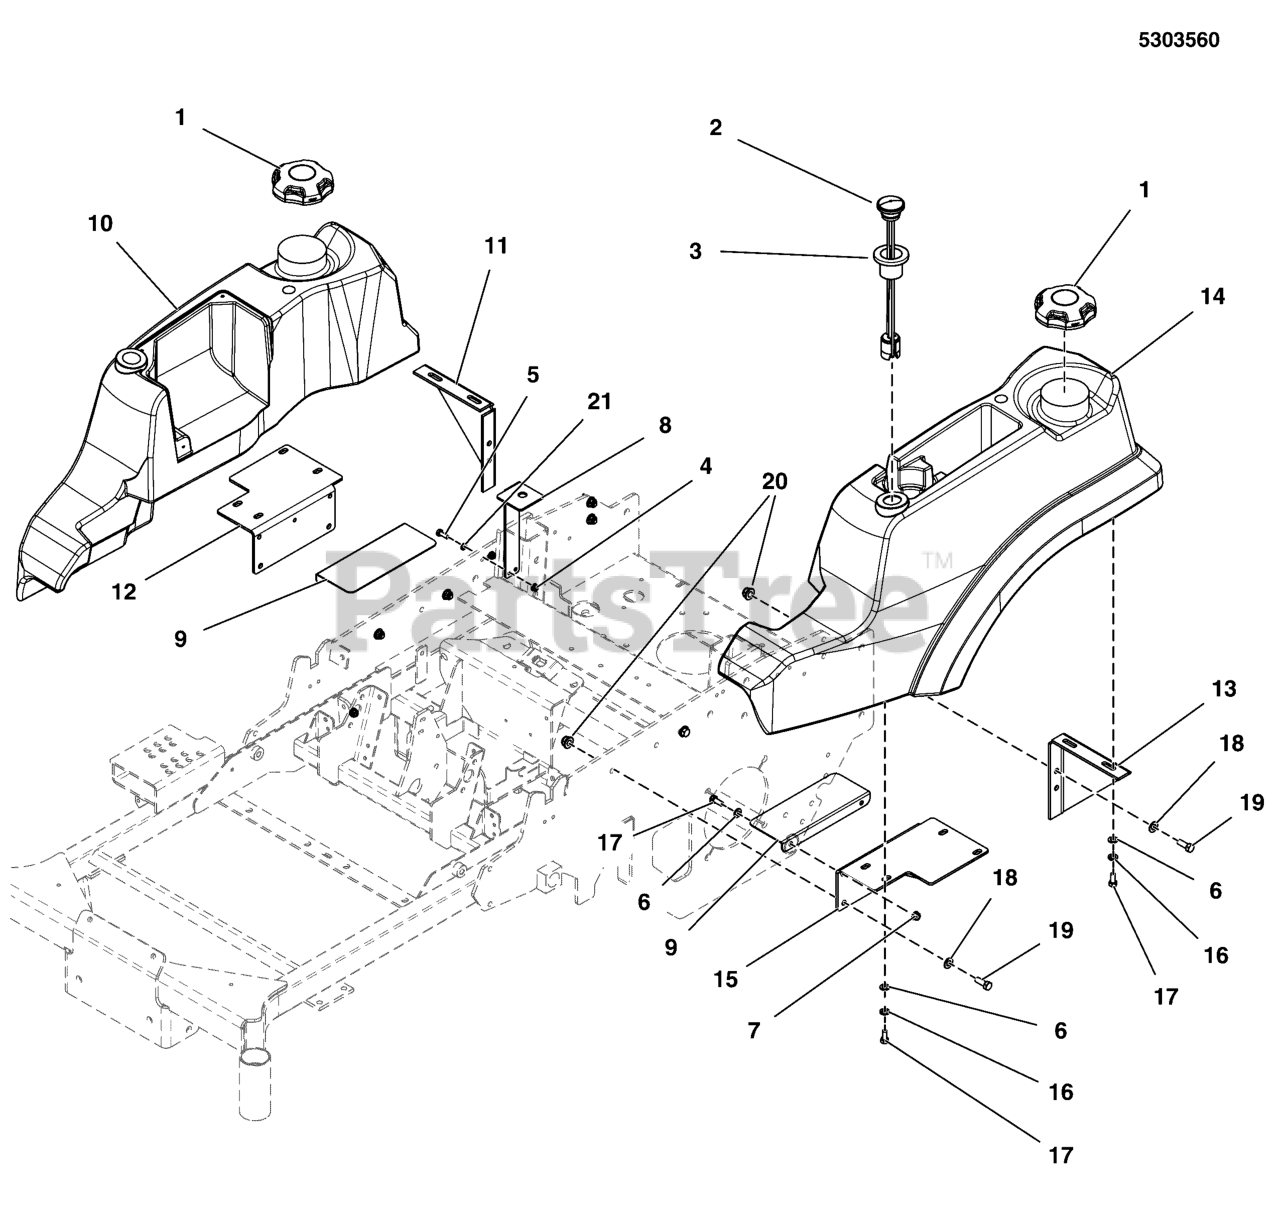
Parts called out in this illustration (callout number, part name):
1	FUEL CAP, 3-1/2", MANAGED VENT OUT, 12"
2	GAUGE, FUEL, 12
3	GROMMET, FUEL GAUGE (SV)
4	NUT, 1/4-20 HEX NYLOCK FLANGE
5	BOLT, 1/4-20 X 3/4 GD5 YZ
6	WASHER, 5/16" SAE
7	NUT, 5/16-18 HEX NYLOCK FLANGE
8	PLATE, FUEL SWITCH - BLK
9	GUARD, FAN - BLK
10	TANK, FUEL, SNP-PRO, RH, 2013
11	MOUNT, REAR TANK, RH - BLK
12	WELD, FUEL TANK MOUNT, S150XT, RH - RED
13	MOUNT, REAR TANK, LH - BLK
14	TANK, FUEL, SNP-PRO, LH, 2013
15	WELD, FUEL TANK MOUNT, S150XT, LH - RED
16	WASHER, 5/16 LOCK CZ
17	BOLT, 5/16-18 X 3/4 GD5
18	WASHER, 3/8 SAE
19	BOLT, 3/8-16 X 1" GD5 CZ
20	NUT, 3/8-16 HEX NYLOCK FLANGE
21	WASHER, 1/4 SAE
